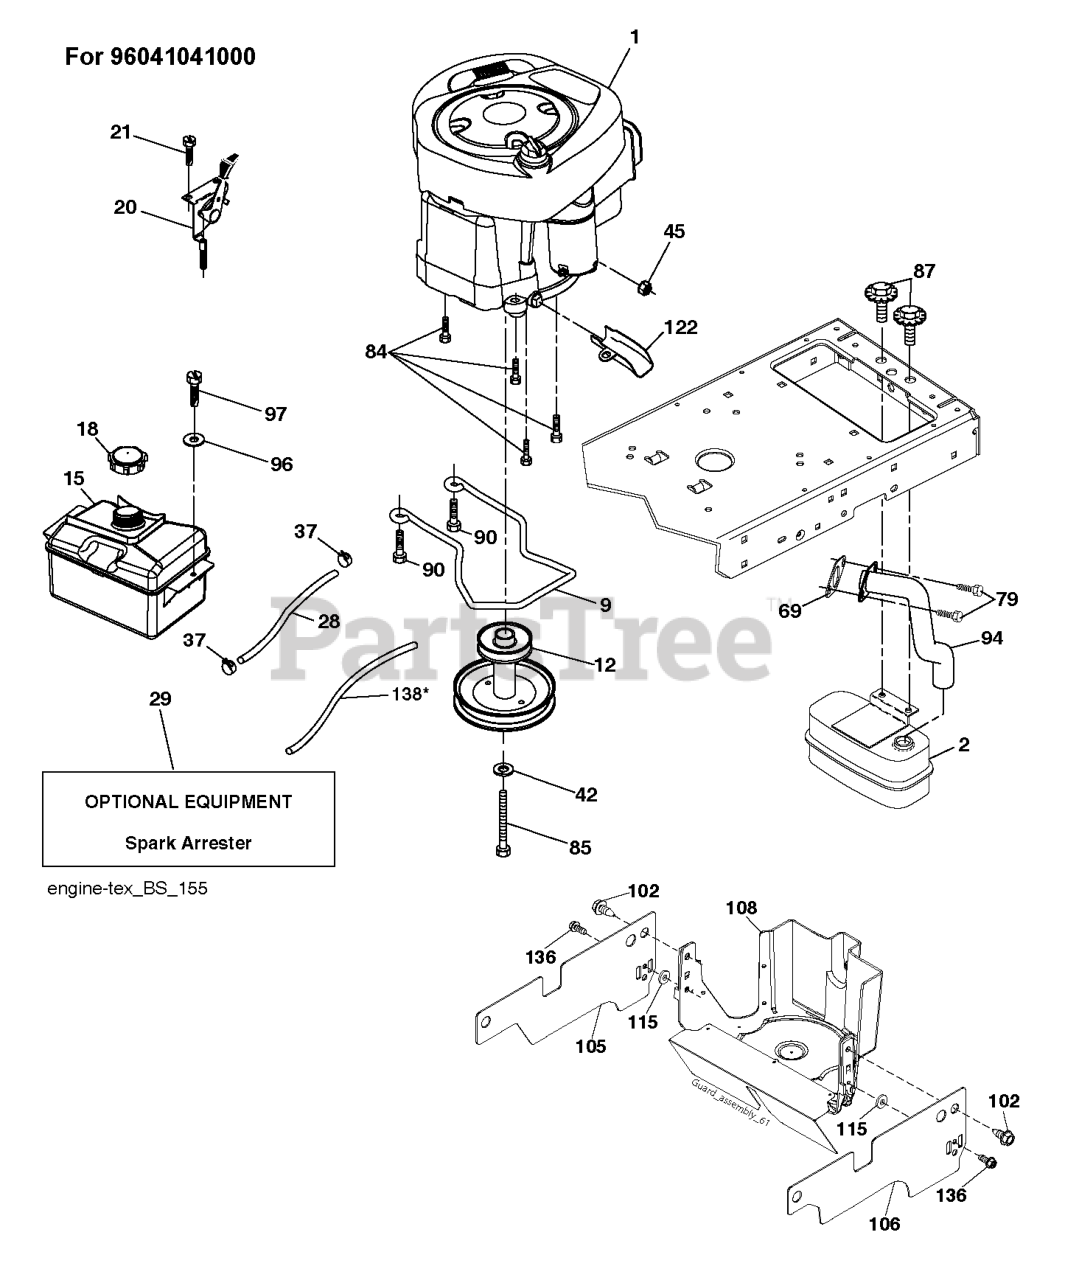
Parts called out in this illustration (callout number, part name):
2	MUFFLER.SINGLE.CYL.KOHL/B&S
9	KEEPER.BELT.ENG.4.25"2.BLT.431
12	ENGINE.PULLEY
15	Tanks
15	FUEL.TANK.ASM.NON-EPA
18	CAP ASM.FUEL.2.25"FR.
20	THROTTLE.COBRA.21".RSTART.BLK
28	LINE.FUEL.20
29	KIT.SPARK ARRESTOR 794945 B&S
37	HOSE CLAMP
69	REPL BY 532 27 22-93
84	SCREW.3/8-16
85	BOLT.HEX.7/16-20X4.GR5.1.5BLUE
87	BOLT.5/16-18UNCX3/4 W/SEMS.BLK
90	SCREW 3/8-16X1
94	EXHAUST.TUBE.B&S.28/31
97	SCREW HEXWSHR 1/4-20X3/4
102	SCREW
105	SHIELD.SIDE.LH.3842"TEX FRN.BK
106	SHIELD.SIDE.LH.3842"TEX FRN.BK
108	COVER ENGINE PULLEY COVER WITH
122	EXTENSION DRAIN OIL
